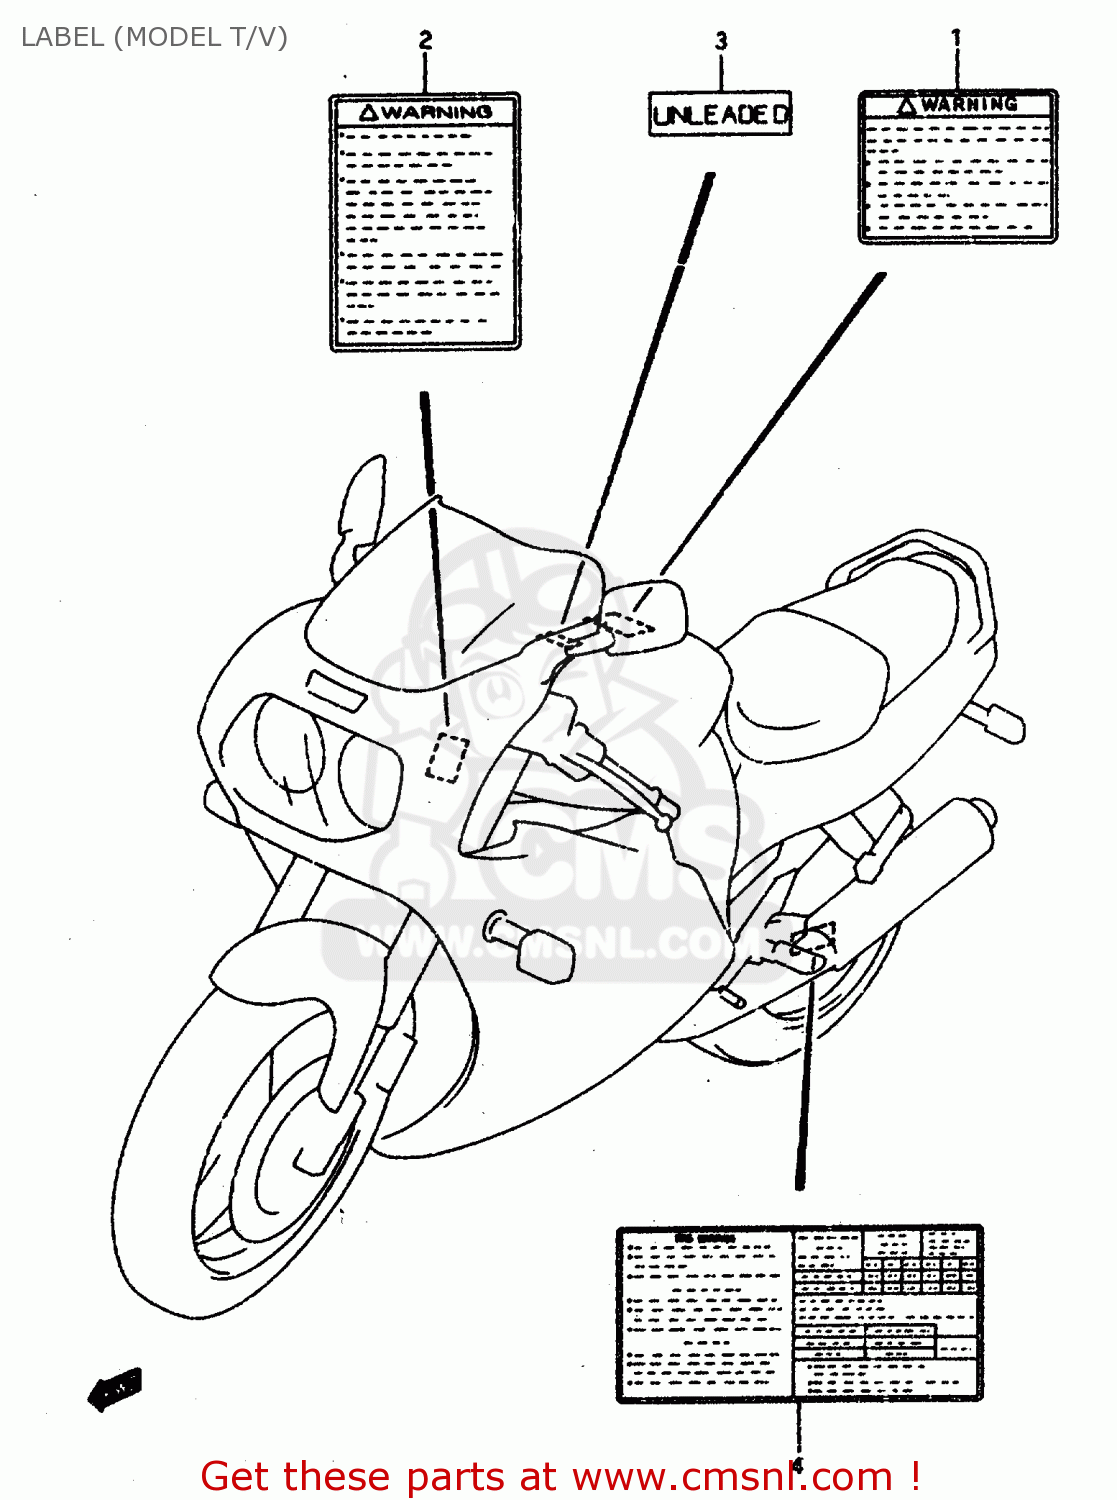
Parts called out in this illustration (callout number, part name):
1	LABEL,WARNING
2	LABEL (WARNING SCREEN)
3	LABEL,CAUTION
4	LABEL (TIRE AIR PRESSURE)
5	MANUAL, OWNER'S
